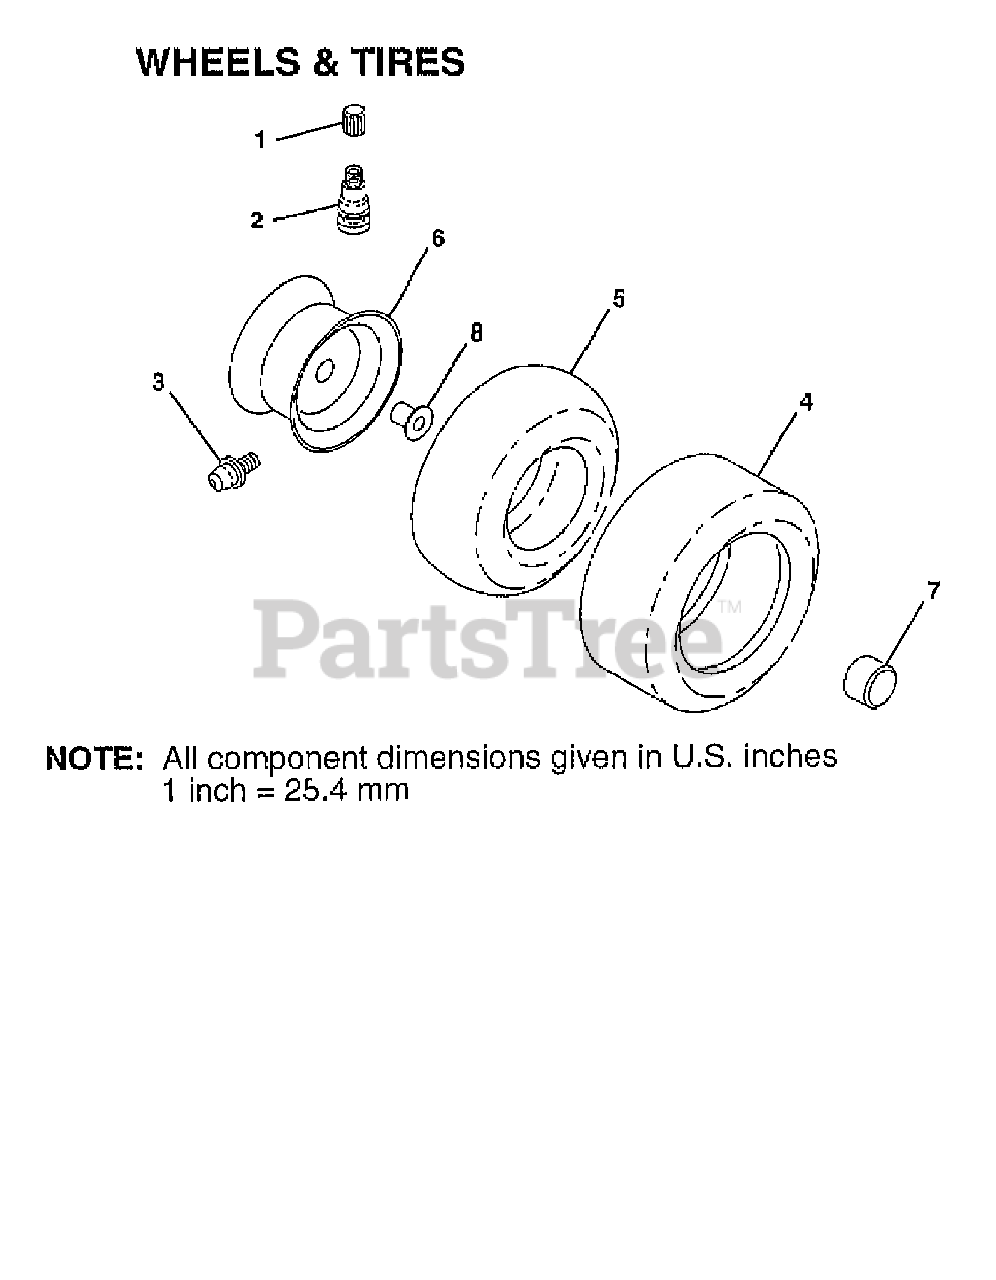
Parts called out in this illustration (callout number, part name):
1	VALVE CAP
2	VALVE STEM LT
3	FITTING LT
4	TIRE HEAVY DUTY
4A	TIRE 20X8-8 TURF SAVER
5	TUBE.5.3/4.5/6
5A	TUBE - UNIVERSAL FOR 8" RIM
6	RIM.ASM.6".FRONT.SILVER
6A	RIM 8" SILVER
7	CAP.HUB.FRONT.LT.BLACK
8	BEARING T
